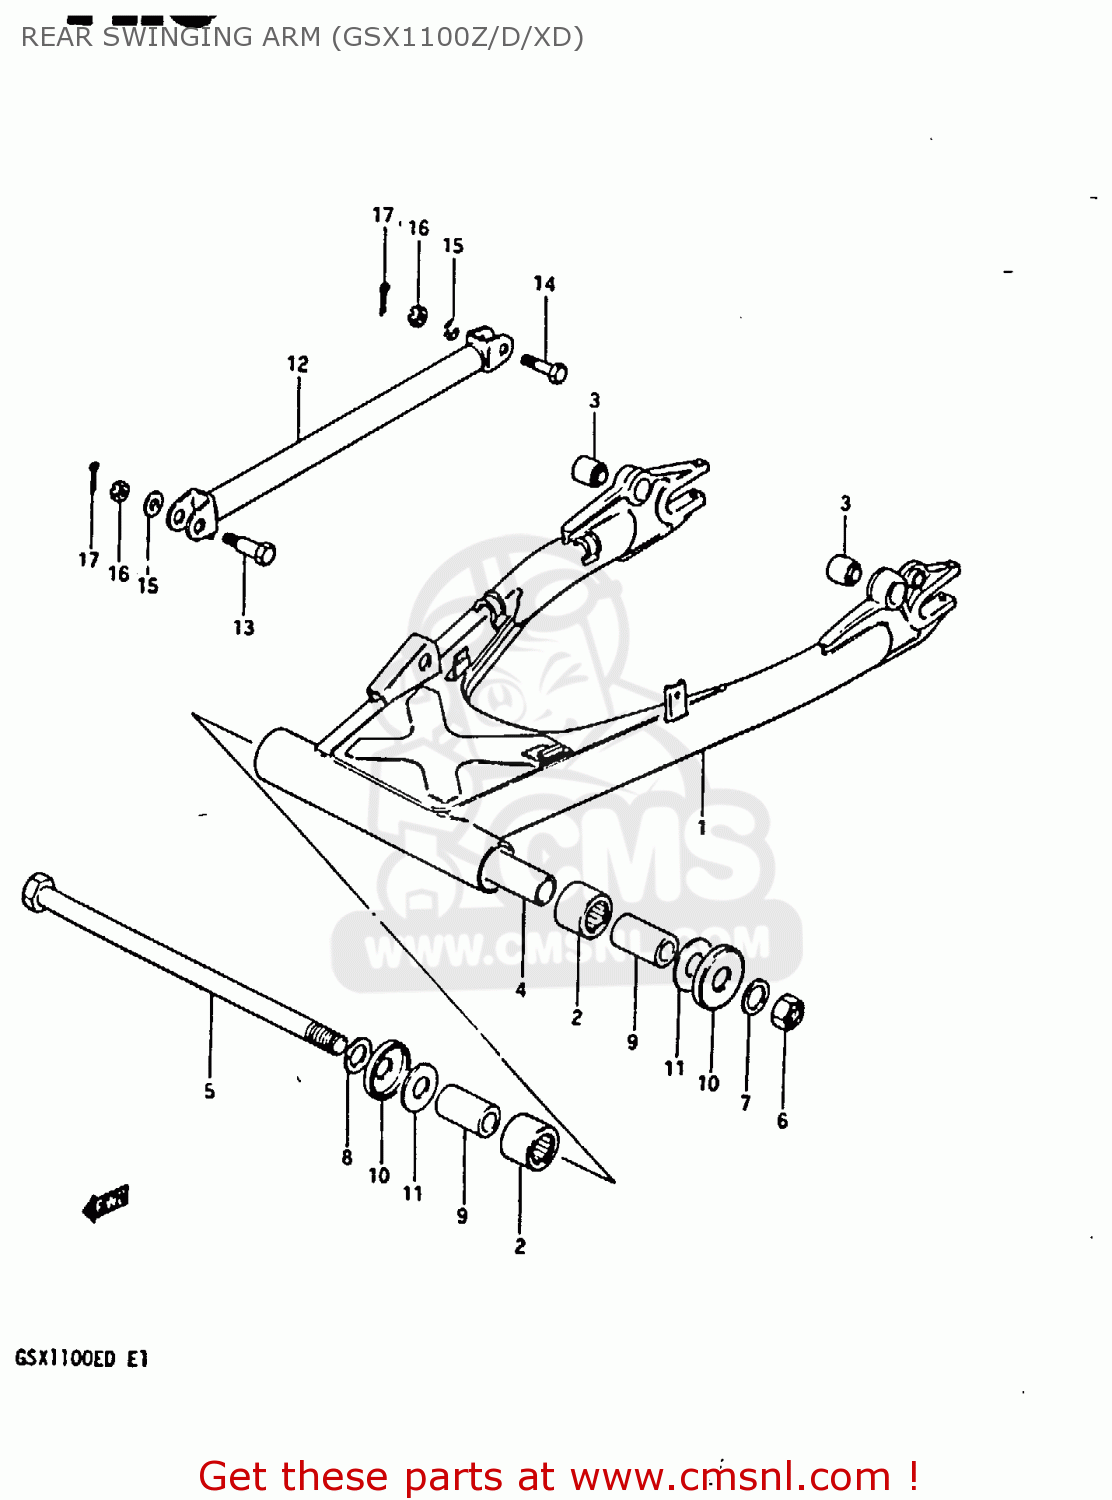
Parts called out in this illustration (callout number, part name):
1	SWING ARM ASSEMBLY,REAR
2	BEARING(25X33X30)
3	BUSH
4	SPACER,RR SWGARM PIVOT CTR
5	SHAFT,REAR SWING ARM
6	NUT 16MM
7	WASHER
8	WASHER
9	SPACER,RR SWGARM PIVOT
10	COVER,RR SWGARM DUST SEAL
11	WASHER
12	LINK,RR TORQUE
13	BOLT
14	BOLT(10X39)
15	WASHER
16	NUT
17	PIN 20X20
